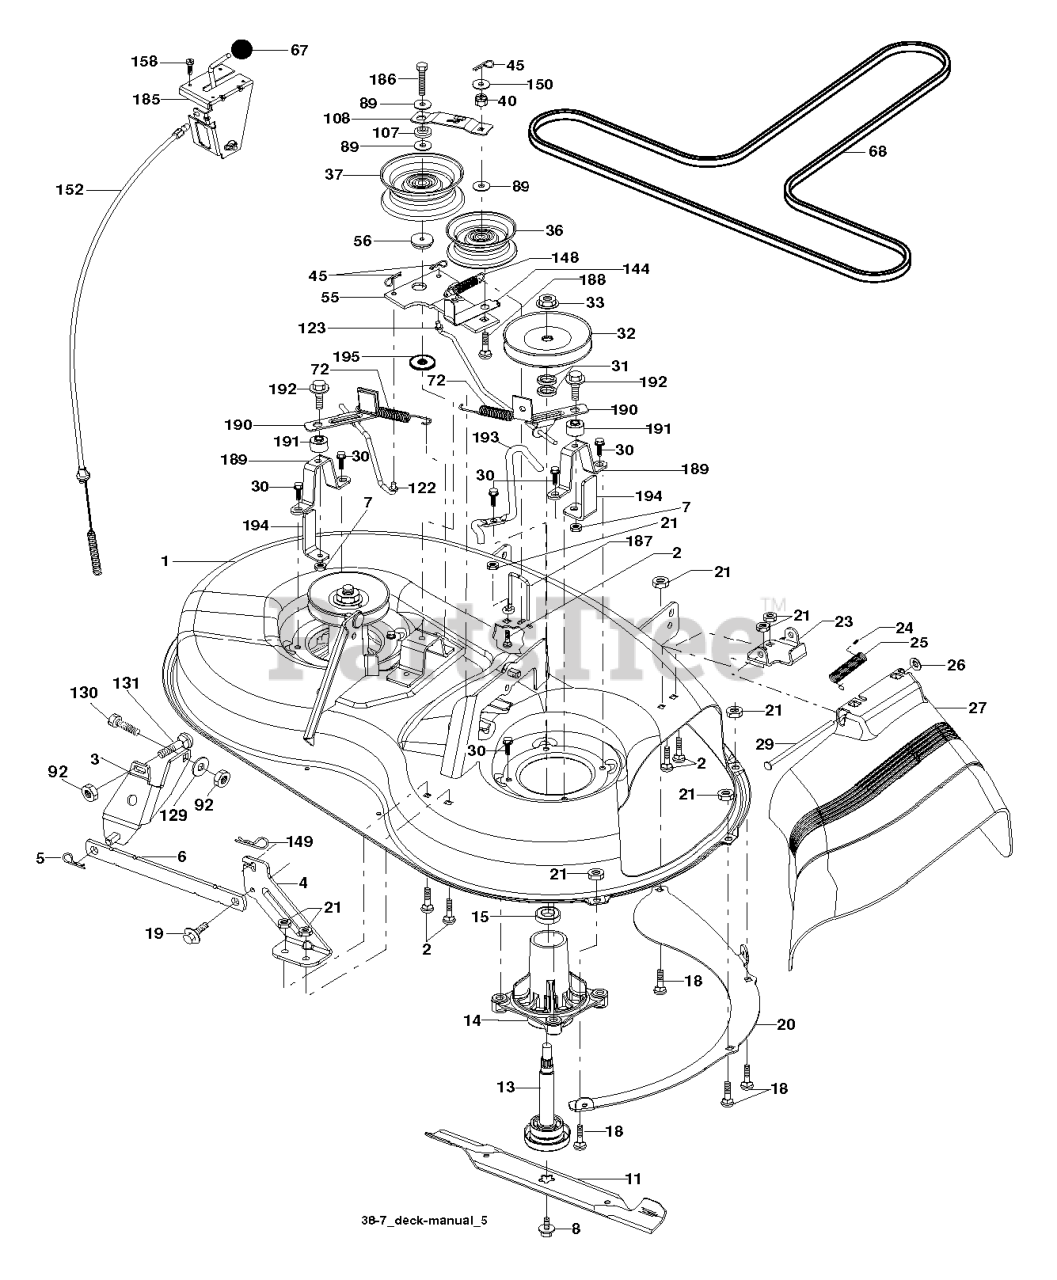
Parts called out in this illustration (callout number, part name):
1	DECK SVCX1 38/94 192556X431
2	RP BOLT 5/16-18 X3/4 ZN/YEL GR
3	BRKT ASM SWAY BAR
4	BRACKET DECK SWAY BAR 38"/42"
5	RETAINER-SPRNG RB
6	BAR SWAY DECK
7	NUT.71038.31-18.HEX.NYLOCK
8	BOLT.WASHER.ASM.7/16-2
11	BLADE 38" PREMIUM
13	SHAFT.ASM.MDRL.N/GREASE.38
14	RP.HOUSING.MANDREL.4PT.
18	BOLT
19	BOLT SHD 5/16-18
20	BAFFLE.VORTEX.FRONT.38"
21	LOCKNUT
23	BRKT.DEFLECTOR.38"2005+
24	CAP-SLEEVE LT
25	SPRING.TORSION.DEFLECT
26	NUT PUSH M
27	SHIELD.DEFLECTOR.MWR.38-7/97CM
29	ROD.HINGE
30	SCREW, WASHER HEAD
31	WASHER.SPACER.MANDREL
32	PULLEY MANDREL
33	NUT.FLANGE.LOCK.TOP
36	FLAT IDLER PULLEY
37	PULLEY.IDLER.FLAT.UNPLATED
45	RETAINER M
56	SPACER.RETAINER.MOWER
67	KNOB T (3/8 HOLE)
68	V-BELT.MOWER.38"2005+
72	SPRING.BRAKE.RETURN.38"
89	WASHER
92	NUT
107	SPACER.IDLER.ARM
108	STIFFENER.IDLER.ARM
122	LINKAGE.BRAKE.LH.38"
123	LINKAGE.BRAKE.RH.38"
129	WASHER
131	BOLT D
144	KEEPER BELT
148	IDLER RETURN SPRING
149	SPRING.RETAINER.YELLOW.ZINC
152	CABLE.CLUTCH.38".SERVICE
158	SCREW
185	HEAD ASM. CABLE CLUTCH
186	SCREW.HXWSH.3/8
187	KEEPER BELT
188	BOLT, CARRIAGE IDLER
189	STAND, BRAKE
190	ARM, BRAKE
191	BRAKE.SPACER.38".DECK
192	BOLT/WASHER ASM 5/16-18
193	KEEPER BELT RH MANDREL
194	GUARD BRAKE
195	WASHER 12/32X2X10GA
